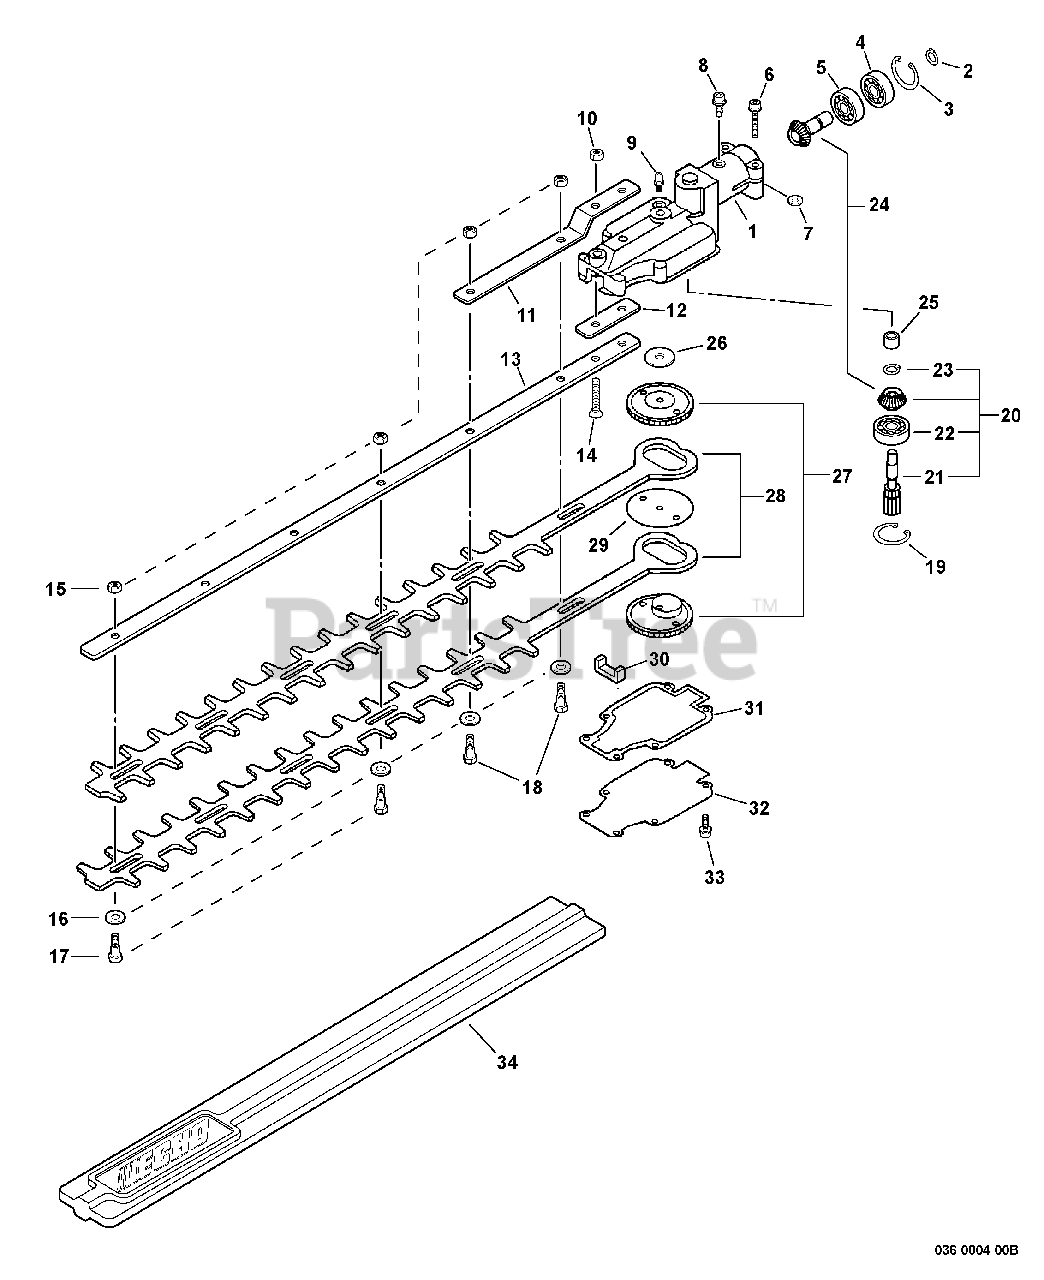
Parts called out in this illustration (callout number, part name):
1	CASE, GEAR - UPPER
2	RING, SNAP Ø12
3	RING, RETAINING Ø24
4	BEARING, BALL 6901Z
5	BEARING, BALL 6901
6	BOLT 5×28
8	BOLT 5×12
9	FITTING, GREASE
10	NUT, HEX M6
11	PLATE, ANGLE
12	SPACER
13	SUPPORT, BLADE
14	SCREW 6×35
16	WASHER 6.5×15.5×0.6
18	BOLT 6×20
19	RING, RETAINING Ø24
20	SPUR GEAR ASSY
21	GEAR, PINION
22	BEARING, BALL 6901
23	RING, RETAINING
24	GEAR SET
25	BEARING, NEEDLE
26	WASHER 6.5×30×0.2
27	GEAR, SPUR
29	WASHER 6.7×54×0.38
31	GASKET, GEAR CASE
32	LID, GEAR CASE
33	BOLT 4×12
34	SCABBARD
